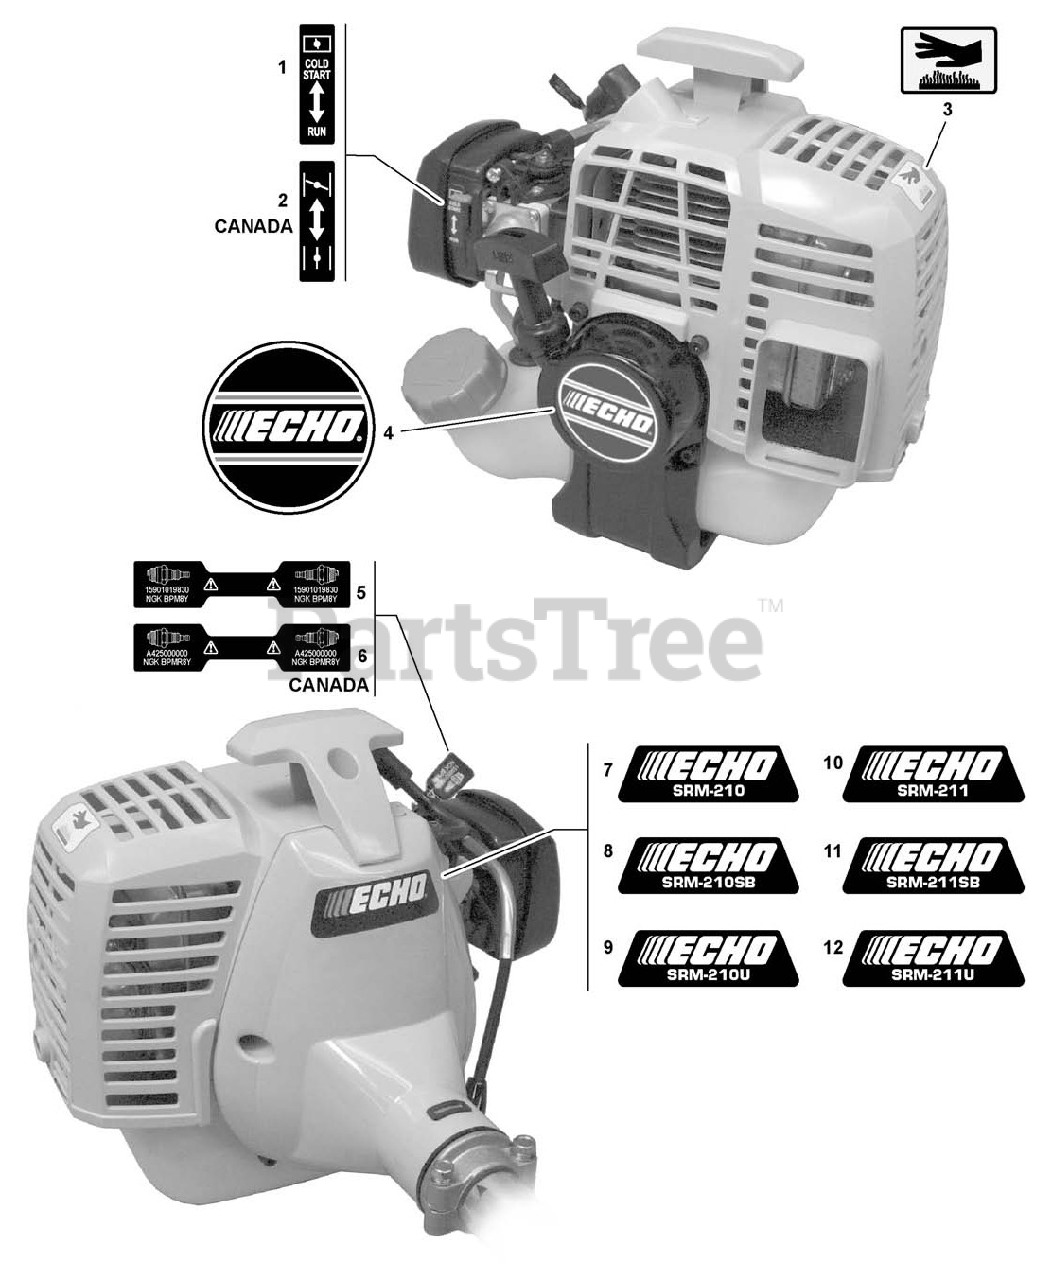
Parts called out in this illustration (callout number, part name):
1	Label - Choke
2	Label - Choke
3	Label - Caution - Hot
4	Label - Echo
5	Label - Spark Plug - BPM-8Y
6	Label - Spark Plug - BPMR-8Y
7	Label - Model - SRM-210
8	Label - Model - SRM-210SB
9	Label - Model - SRM-210U
10	Label - Model - SRM-211
11	Label - Model - SRM-211SB
12	Label - Model - SRM-211U
